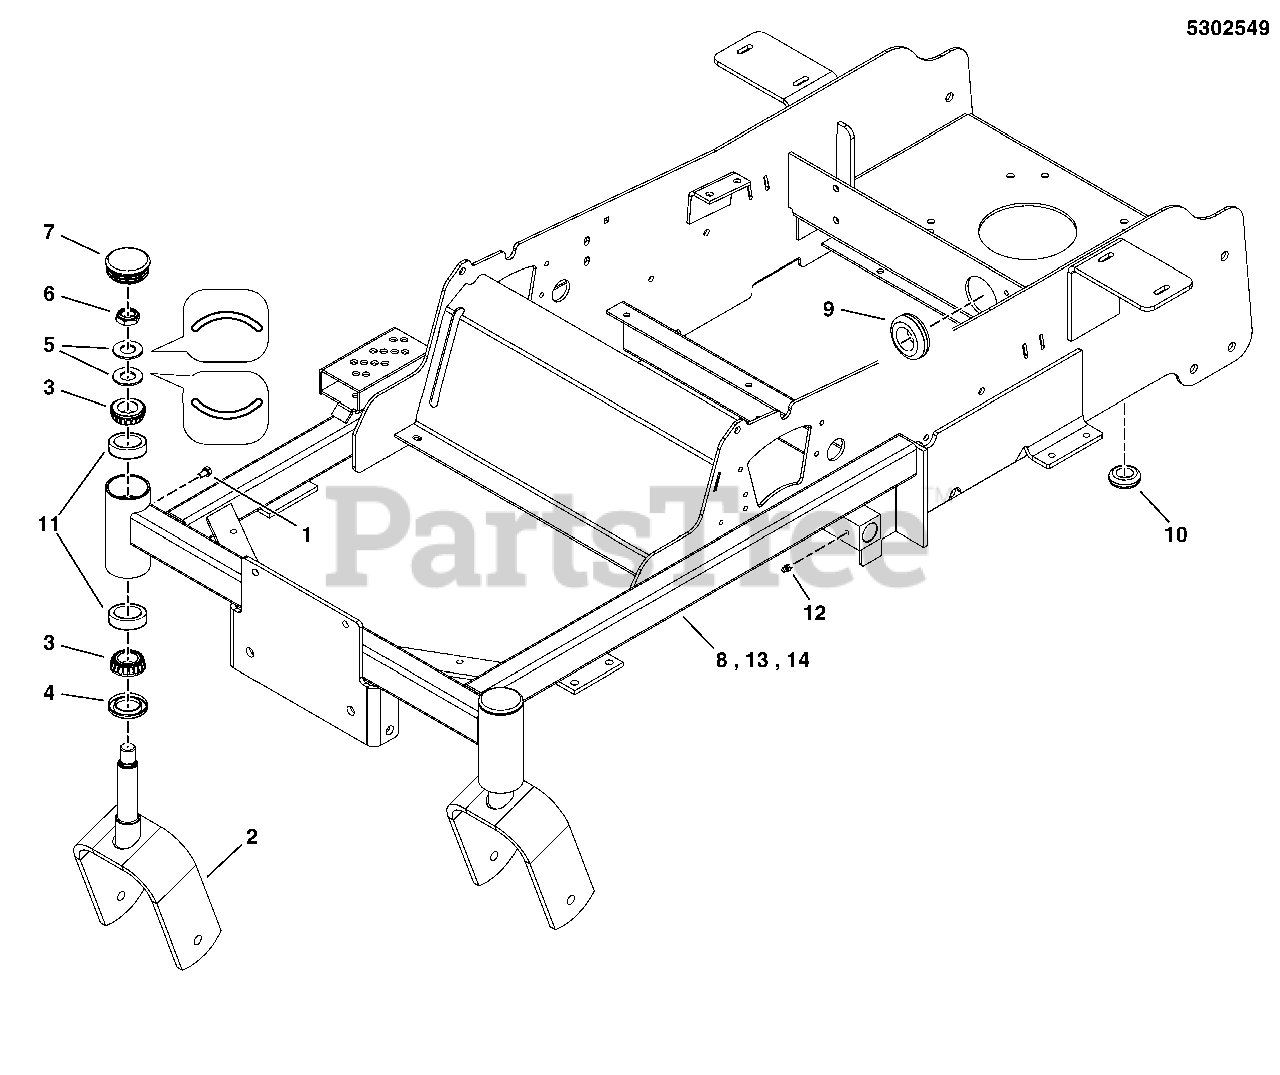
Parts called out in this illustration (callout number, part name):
1	BOLT, 1/4-28 X 1/2, GD5 YZ
2	WELD, CASTER YOKE, IS500Z
3	BEARING, TAPERED ROLLER, 1"
4	SEAL, GREASE
5	WASHER, BELLEVILLE - 1.500 X .755
6	NUT, 3/4-16, HEX JAM NYLON LOCK
7	CAP, LOW PROFILE, STEEL
8	WELD, MAIN FRAME, 48 - RED
9	GROMMET, 2" ID
10	GROMMET, 7/8
11	CUP, BEARING (SV)
12	GREASE FITTING, 1/4-28 STRAIGHT
13	WELD, MAIN FRAME, 50XT-48"
14	WELD, MAIN FRAME, 50XT-48"
